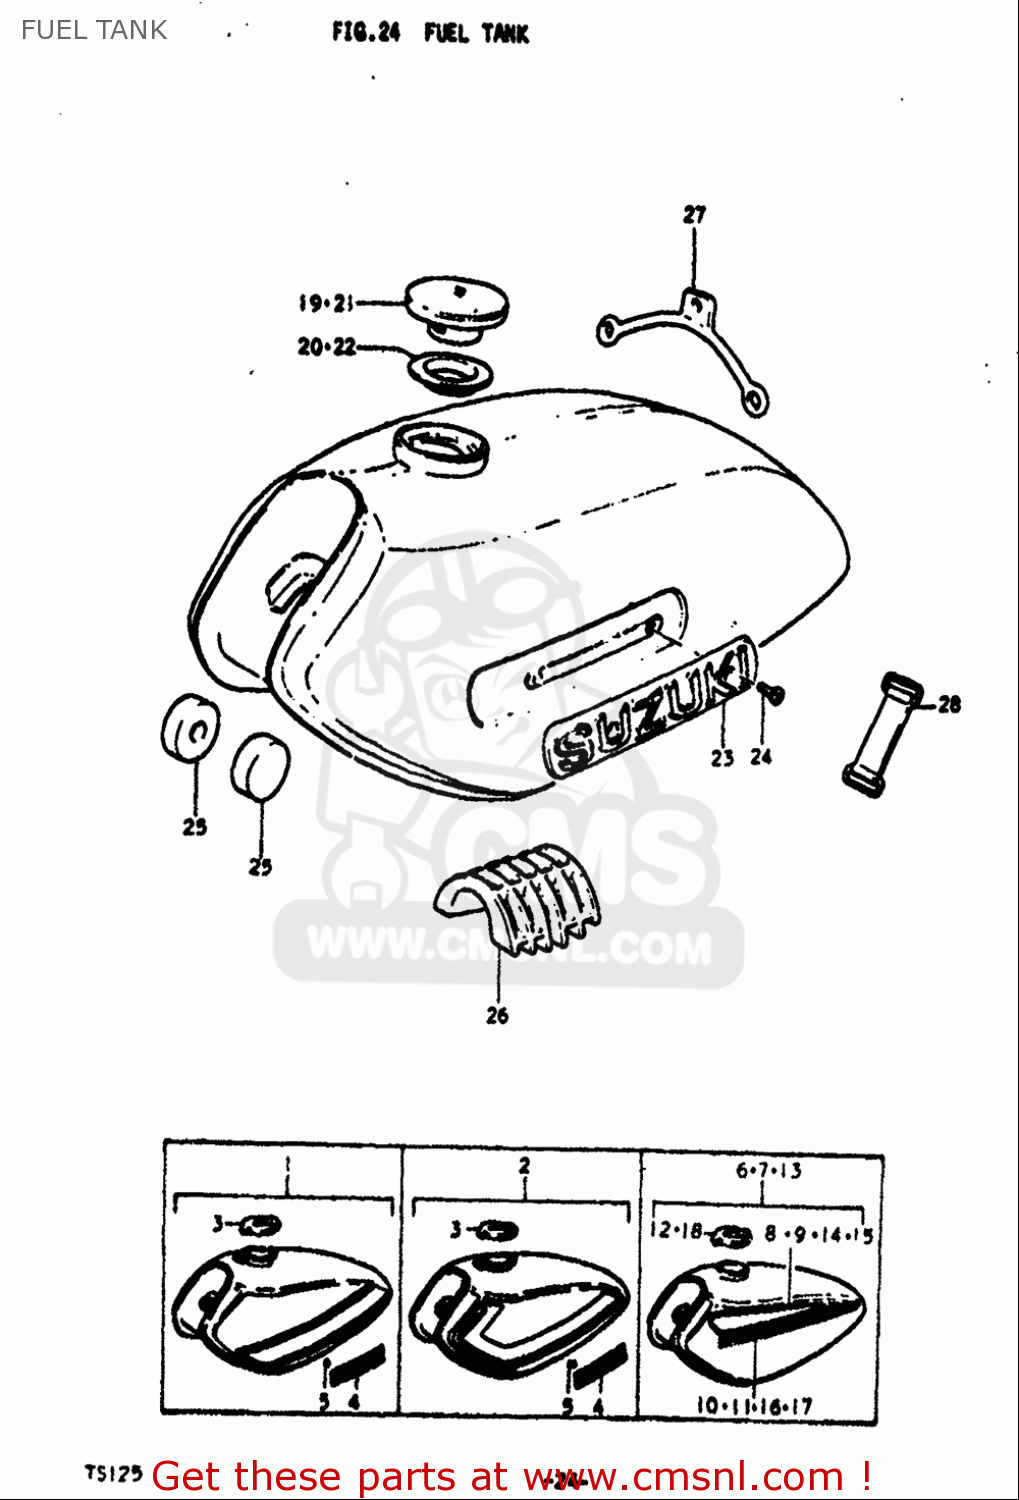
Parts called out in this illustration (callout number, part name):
3	CAP ASSY,FUEL TANK
5	NUT
12	CAP ASSY,FUEL TANK
18	CAP ASSY,FUEL TANK
19	CAP ASSY,FUEL TANK FILLER
21	CAP ASSY,FUEL TANK FILLER
22	GASKET (NAS)
24	SCREW
25	CUSHION
26	CUSHION
28	BAND
